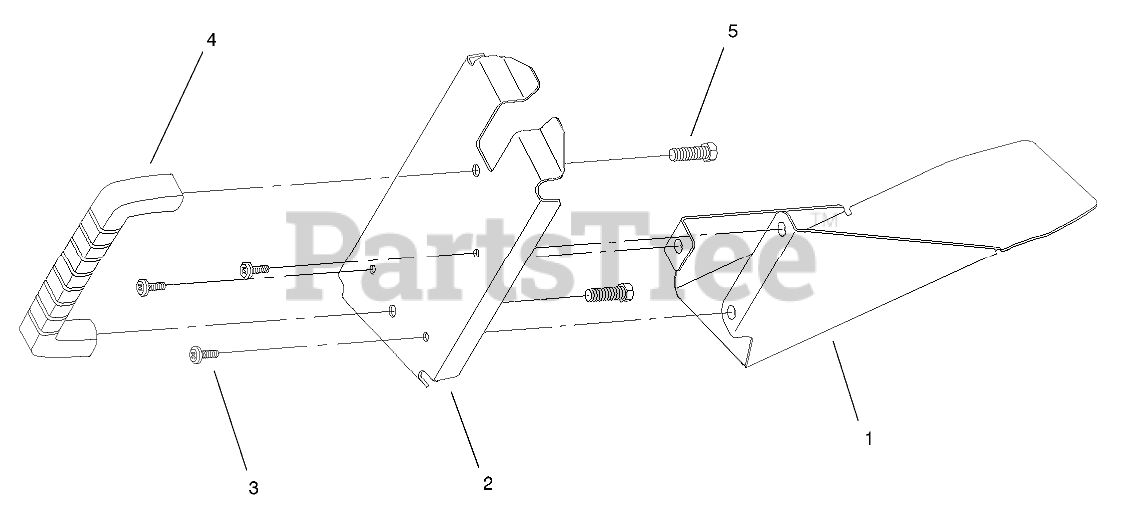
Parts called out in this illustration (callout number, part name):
1	SHIELD - DISCHARGE PLUG
2	COVER - DISCHARGE PLUG
4	HANDLE-DOOR
5	SCREW-HWH
